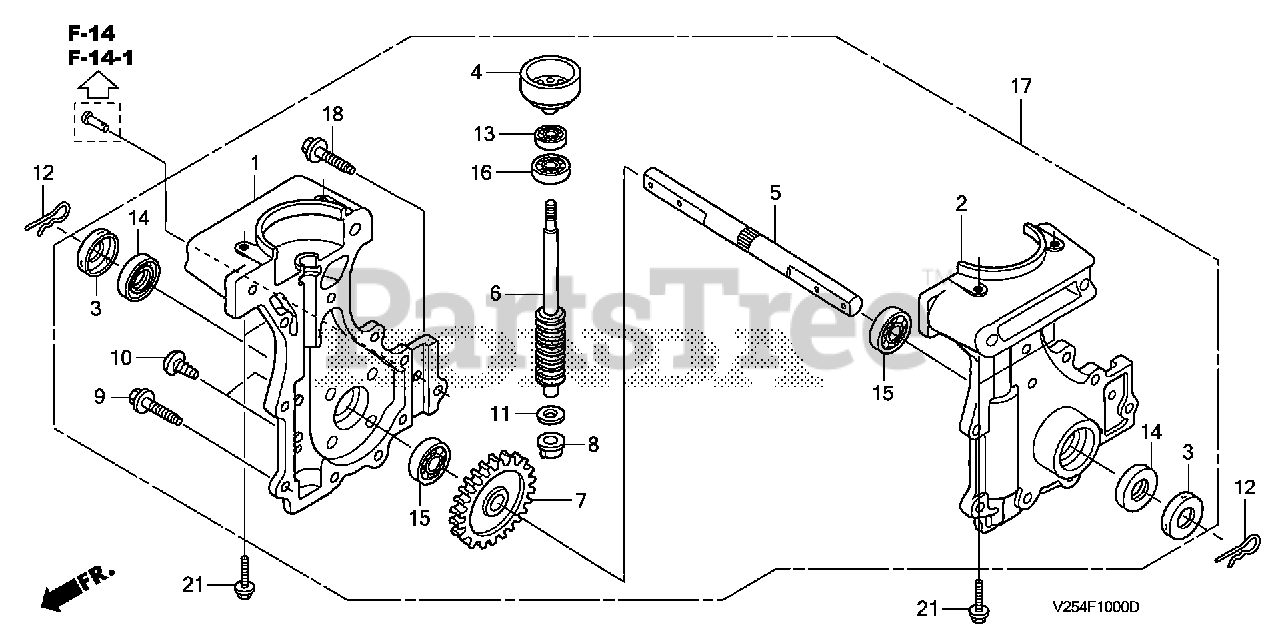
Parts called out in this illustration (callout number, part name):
1	CASE, R. TRANSMISSION
2	CASE, L. TRANSMISSION
3	GUARD, GRASS
4	CLUTCH OUTER
5	SHAFT, TINE
6	GEAR, DRIVE
7	GEAR, DRIVEN (34T)
8	BUSH, DRIVESHAFT
9	BOLT, FLANGE (6X23)
10	SCREW, SELF-TAPPING (1/4-20X1/2)
11	WASHER (10X24)
12	PIN, LOCK (17MM)
13	BEARING, RADIAL BALL (628)
14	OIL SEAL (17X40X8)
15	BEARING, RADIAL BALL (6203)
16	BEARING, RADIAL BALL (6200)
17	TRANSMISSION ASSY.
18	BOLT, FLANGE (6X20) (CT200)
21	BOLT, FLANGE (6X45)
